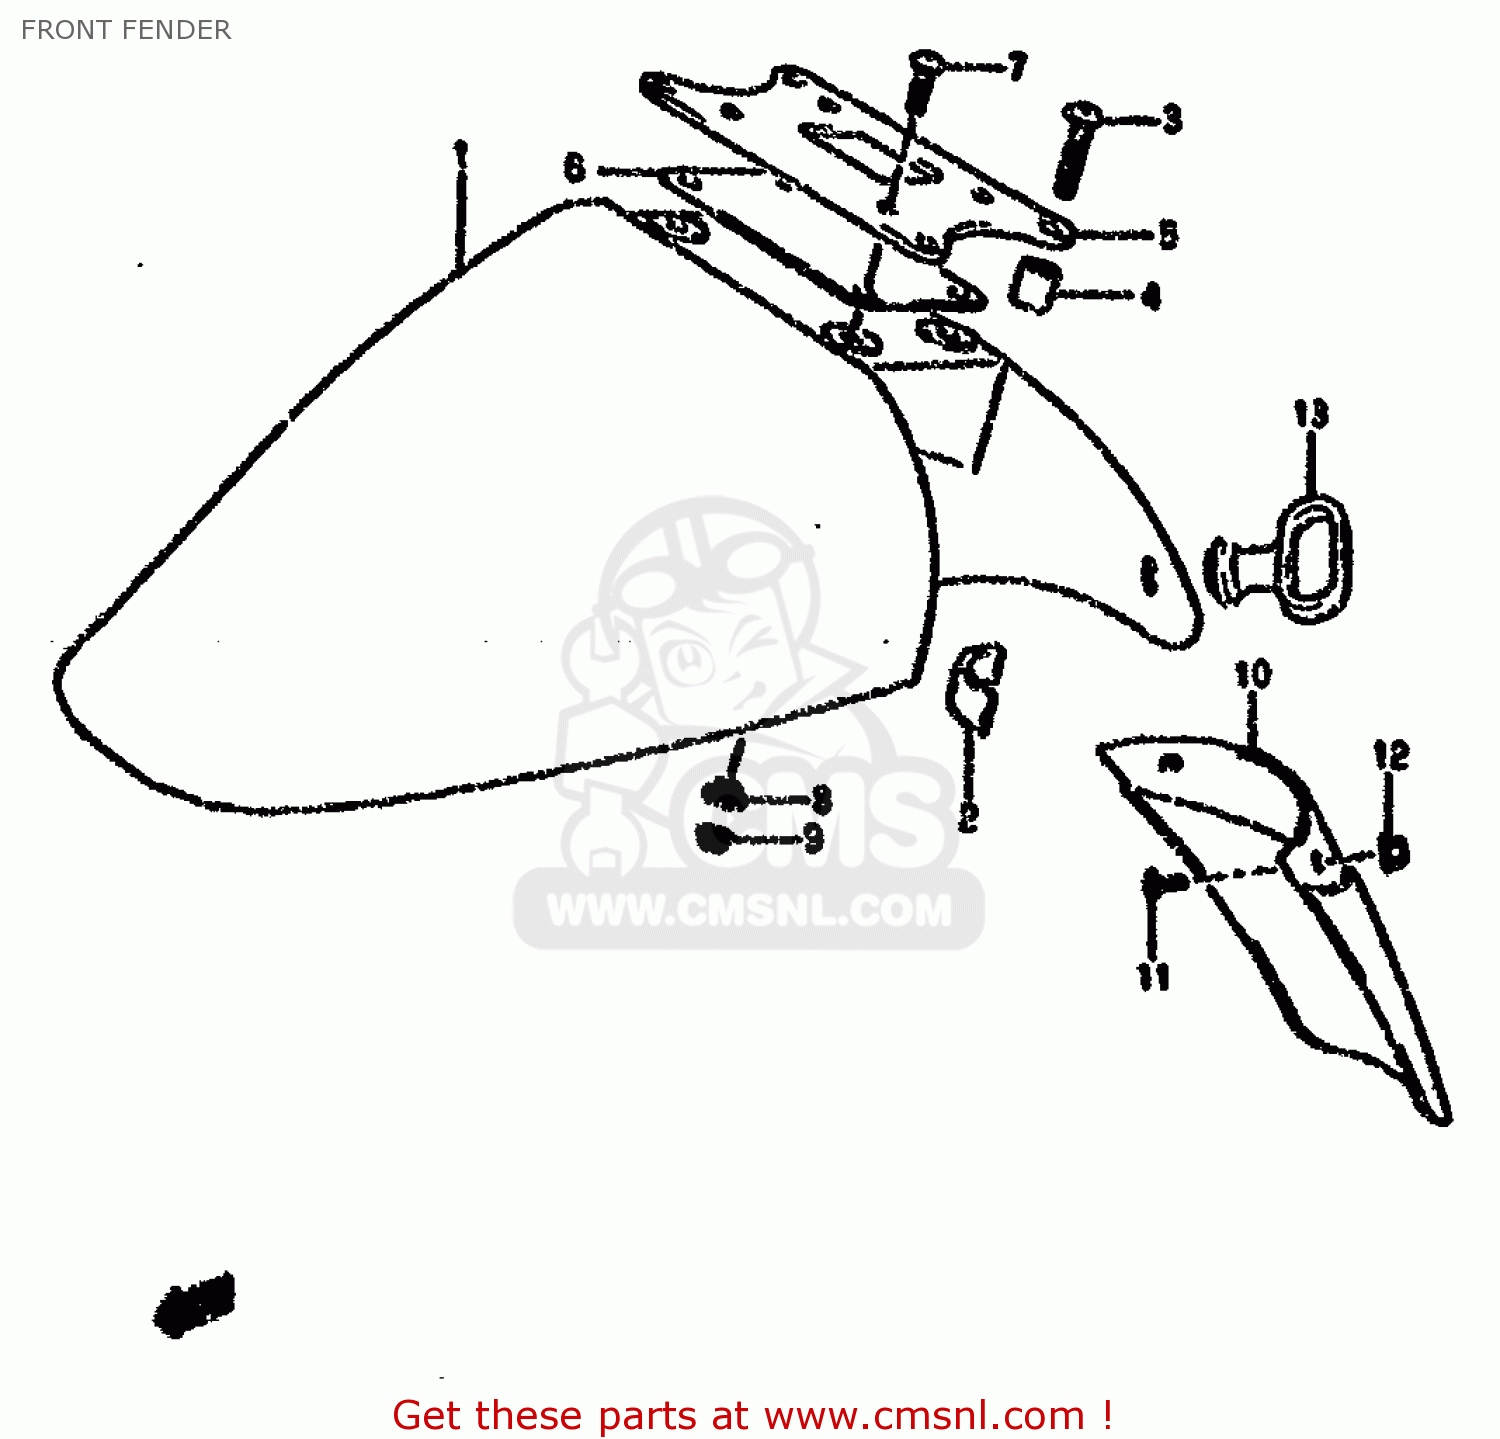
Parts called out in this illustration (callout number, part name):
1	FENDER,FRONT
2	CUSHION,BODY COWLING
3	SCREW(6X30)
4	SPACER (6.5X11.5X15.5)
5	BRACE,FR FENDER
6	PLATE,FR FENDER
7	SCREW(5X16)
8	WASHER
9	NUT
10	EXTENSION,FR FENDER
11	SCREW
12	NUT
13	GUIDE,CABLE
